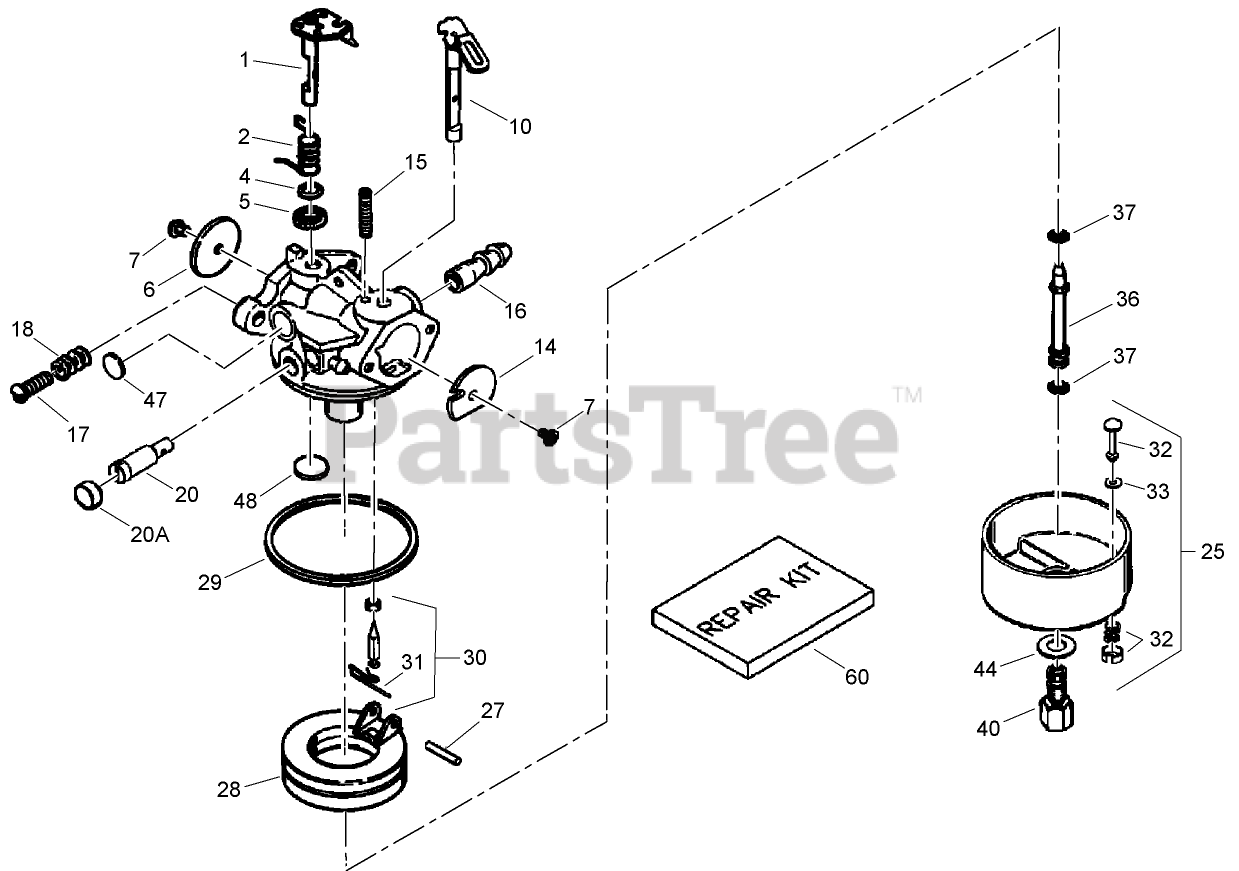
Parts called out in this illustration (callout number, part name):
1	Throttle Shaft and Lever ASM
2	Spring-Return, Throttle
4	Washer-Seal, Dust
5	Seal-Dust
6	Shutter-Throttle
7	Screw-Shutter
10	Choke Shaft and Lever ASM
14	Shutter-Choke
15	Spring-Positioning, Choke
16	Fitting-Fuel
17	Screw-Throttle Crack and Idle Speed
18	Spring-Tension
20	Screw-Restrictor, Idle
20A	Cap-Screw, Idle Restrictor
25	Float Bowl Asm. (Incl. Ref. # 32, 33)
25	Bowl-Float (no drain)
27	Shaft-Float
28	Float (Plastic)
29	O Ring-Bowl, Float
30	Inlet Needle, Seat Clip Assy. (Incl. No. 13)
31	Clip-Spring
32	Bowl Drain ASM
33	Gasket-Plunger, Drain
36	Tube-Nozzle, Main
37	O-Ring
40	Nut-Bowl, High Speed
44	Washer-Nut, Bowl
47	Plug-Welch, Idle Mixture Well
48	Plug-Welch, Atmospheric Vent
60	Repair Kit
